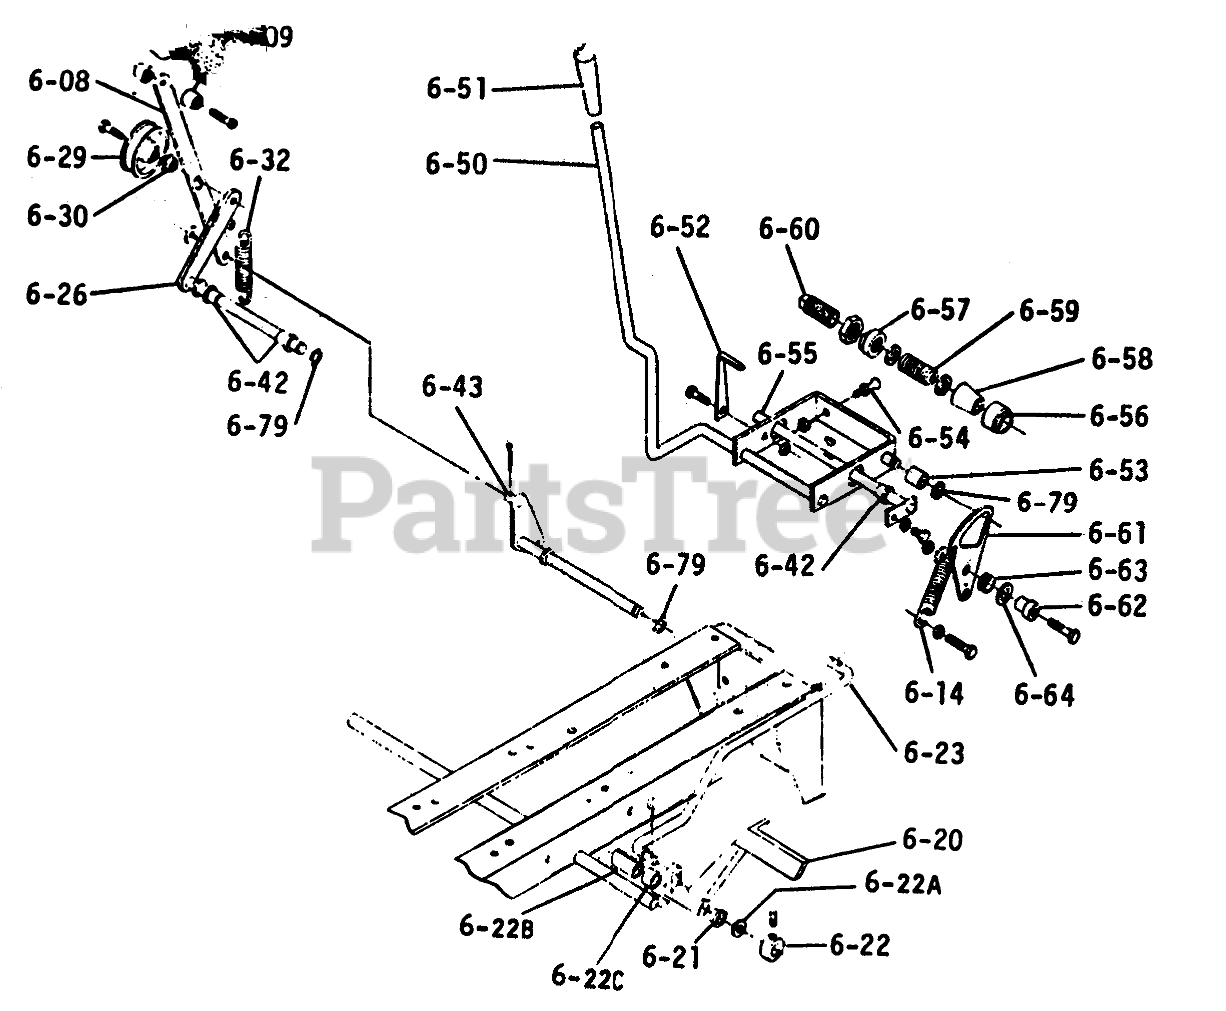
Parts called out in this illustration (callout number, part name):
6-08	HANDLE R (NS)
6-09	Knob-Plain Bolt Hole (C10, C12, B14)
6-14	Spring
6-20	Pedal
6-21	BUSHING
6-22	Collar
6-22A	WASHER-BOWED
6-22B	Spacer (Split)
6-22C	Spacer
6-23	Gasket
6-26	Idler Arm
6-29	Idler Pulley
6-30	SPACER-BRAKE LINK
6-32	SPRING-EXTENSION
6-42	BUSHING-FLANGED
6-43	ever Brake
6-50	Cam Control Arm
6-51	KNOB
6-52	Indicator-Speed
6-53	Bearing
6-54	PIN
6-55	Cam Pivot Rod
6-56	FRICTION COLLAR
6-57	COLLAR BRKT PIVOT
6-58	FRICTION CONE
6-59	SPRING FRICTION
6-60	Collar Friction
6-61	Cam Plate
6-62	Spacer
6-63	NYLINER BUSHING
6-64	SHIM-WASHER
6-79	E Ring
